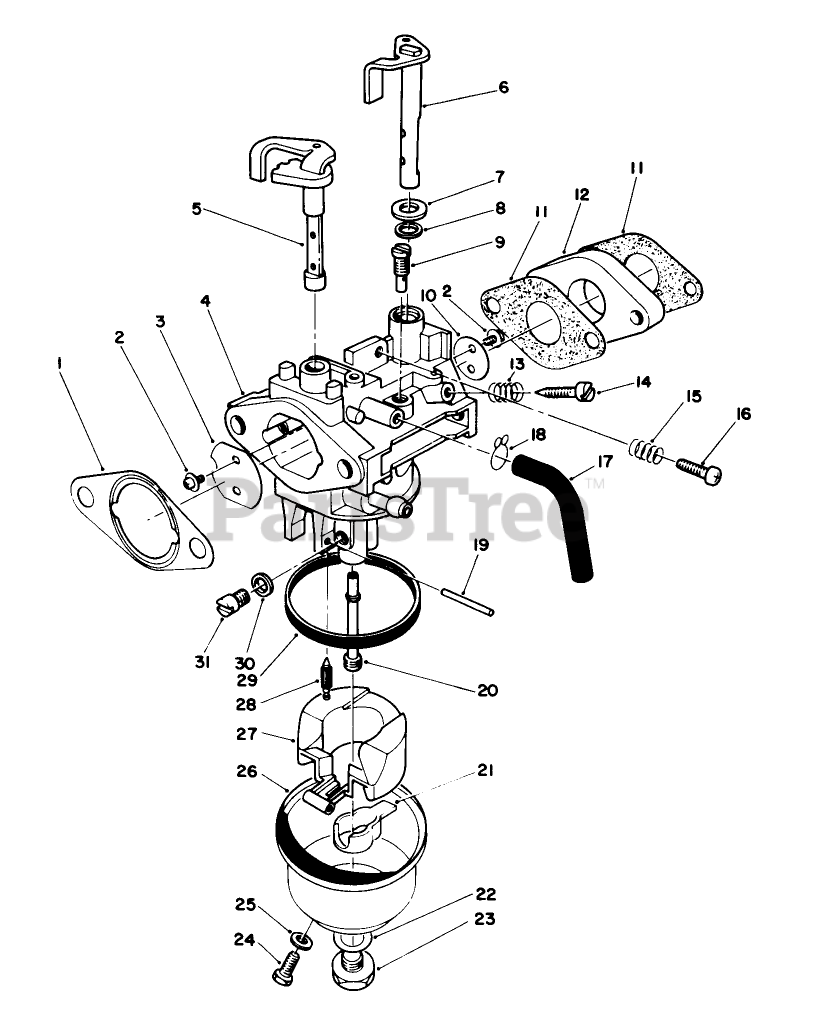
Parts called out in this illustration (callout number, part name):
1	GASKET F/W ENGINE
3	VALVE
4	Body-Carburetor
9	PILOT JET
10	VALVE
12	CARB INSULATOR
13	SPRING-PILOT SCREW
14	ADJUSTER
16	SCREW
22	GASKET
23	SCREW
24	SCREW
25	GASKET
27	FLOAT
29	FLOAT BOWL GASKET
31	MAIN JET
